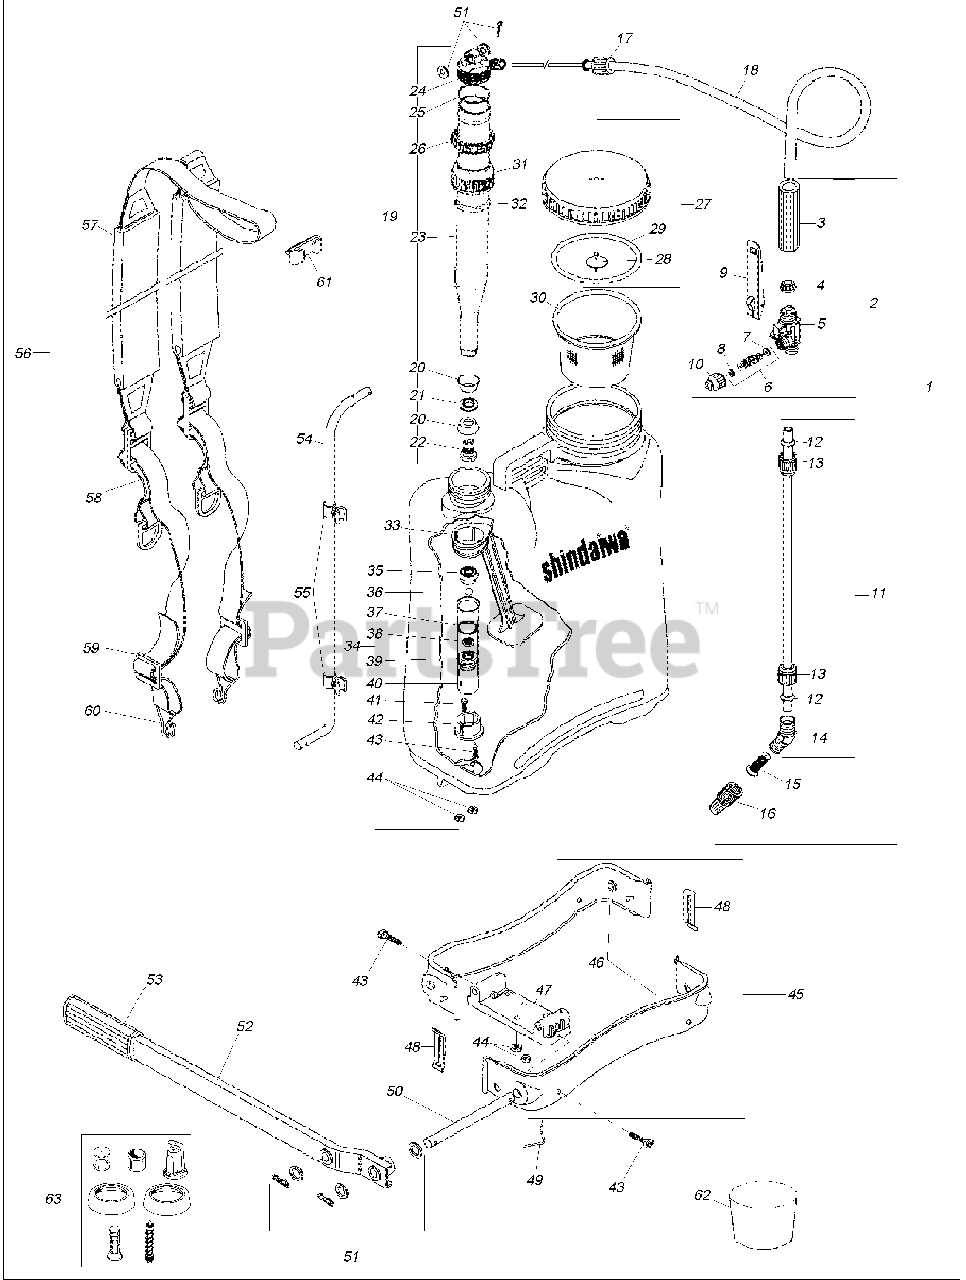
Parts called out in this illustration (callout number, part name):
1	SPRAY WAND ASSY
2	TRIGGER VALVE ASSY
3	HANDLE, TRIGGER VALVE
5	TRIGGER VALVE BODY
6	TRIGGER VALVE NEEDLE ASSY
7	SEAL - LOWER
8	SEAL - UPPER
9	TRIGGER
10	TRIGGER VALVE CAP ASSY
11	Wand Tube/Elbow ASSY
12	CONE PACKING
13	SCREW
14	ELBOW
15	FILTER, NOZZLE
16	ADJUSTABLE CONE NOZZLE
17	NUT - 20X1.5
18	HOSE/DIP TUBE ASSY
19	CHAMBER ASSY
21	Piston Cup Spacer
22	VALVE
23	BODY, CHAMBER
24	COVER, CHAMBER
25	O-RING
26	NUT - CHAMBER
27	CAP ASSY
29	GASKET, CAP
30	STRAINER, DEBRIS
31	Packing Ring Nut
33	AGITATOR
34	CYLINDER ASSY
35	BALL, LOCK
36	BALL
37	O-RING
38	SEAT, BALL
39	SEAT, VALVE
40	CYLINDER
41	BOLT - 6-20 X 1"
42	BASE, CYLINDER
43	SCREW - 14-3/4
44	NUT - FLANGE
45	Split Base ASSY
46	Half Base
49	PIN - LOCKING
50	LEVER, PUMP
51	HARDWARE PACK
52	PUMP LEVER ASSY
54	PUMP LEVER CONNECTING ROD
55	SPRAY WAND HOLDING CLIP
56	STRAP ASSY
57	PAD, SHOULDER
58	STRAP, BACKPACK
59	BUCKLE, STRAP - LOWER
60	Lower Strap Hook
61	CARRYING STRAPS LOCK
62	CALIBRATED MEASURING CUP
63	Standard Repair and Nozzle Kit
